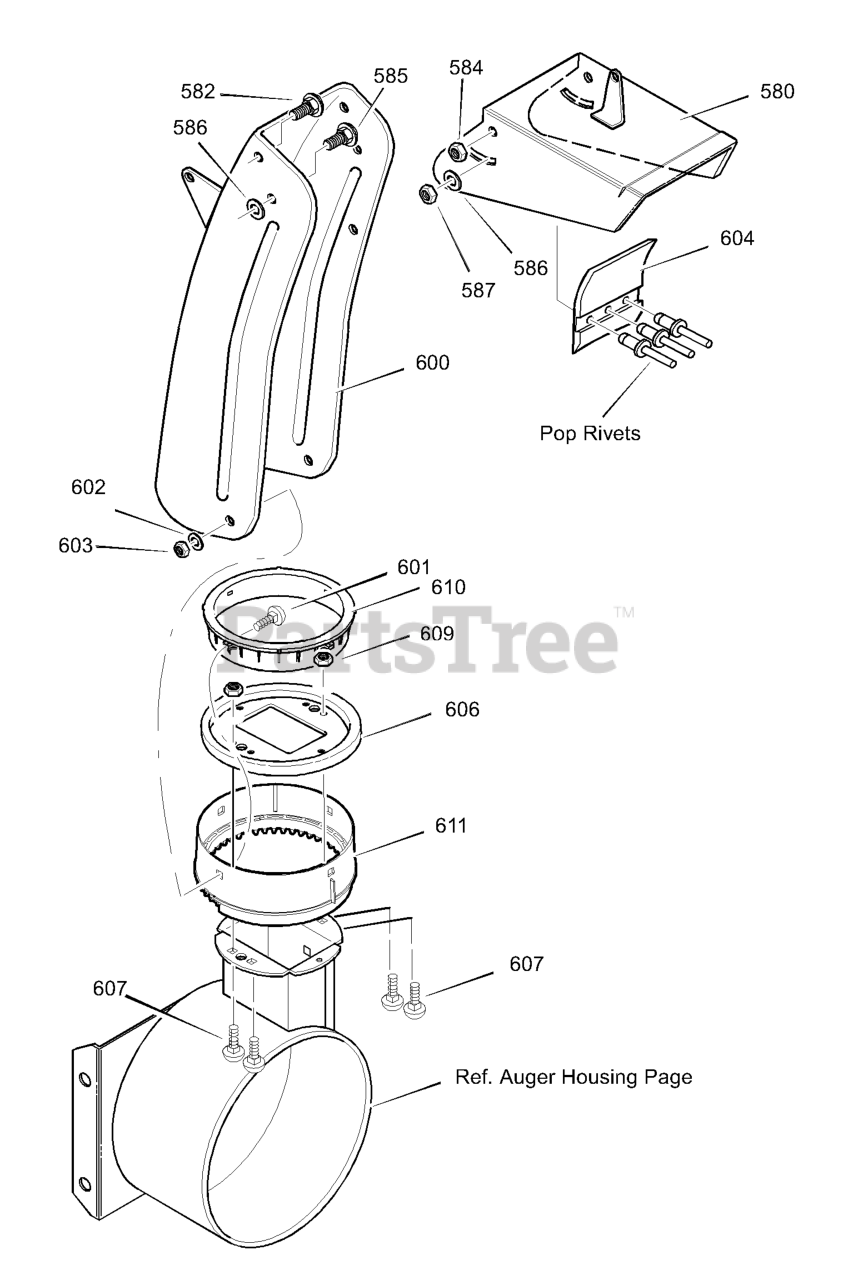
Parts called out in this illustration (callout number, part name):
580	CHUTE, UPPER W/REMOTE
582	SCREW, 5/16-18 x 0.75
584	NUT, 5/16-18 NYLOCK
585	SCREW, 5/16-18 x 0.75
586	PLASTIC WASHER
587	NUT, 5/16-18 NYLOCK
600	CHUTE, LOWER W/REMOTE
601	BOLT, 5/16-18 x 1.00 CARRGE
602	WASHER, FLAT
603	NUT, 5/16-18 NYLOCK
606	CHUTE COLLAR
607	BOLT, 1/4-20- x .75 CARRGE
609	NUT, 1/4-20 NYLOCK
610	RETAINER, RING INNER
611	RETAINER, RING OUTER
